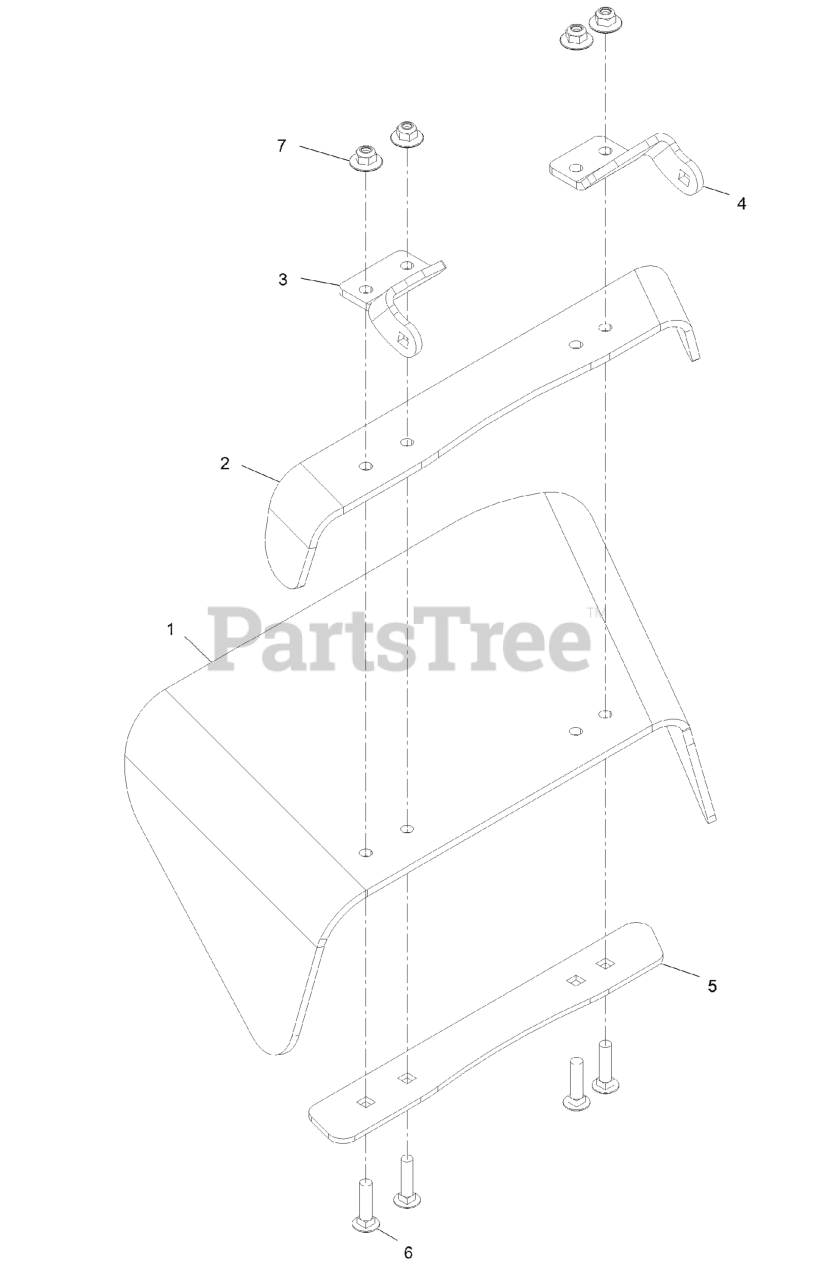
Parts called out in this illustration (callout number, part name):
1	DEFLECTOR-RUBBER
2	BRACKET-TOP DEFLECTOR
3	BRACKET-DEFLECTOR
4	BRACKET-DEFLECTOR
5	STRAP-BOTTOM DEFLECTOR
6	SCREW-CARR
7	Nut-Nyloc 3/8-16 Flg
